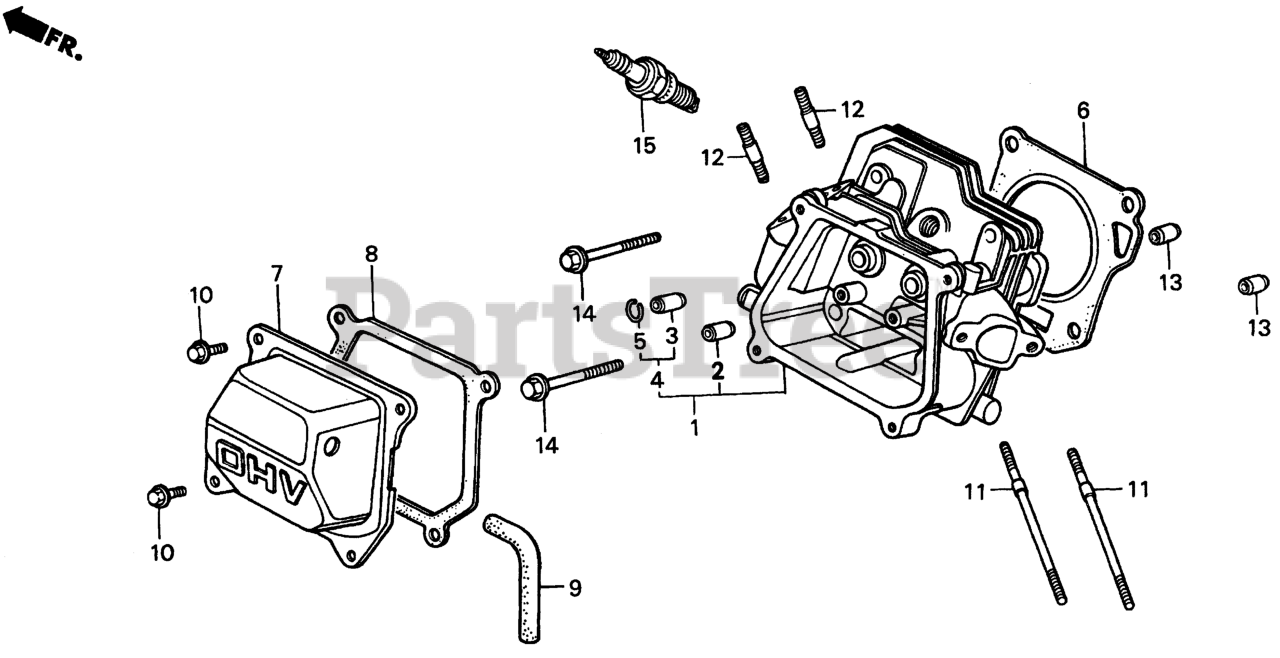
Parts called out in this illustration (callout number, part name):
1	CYLINDER HEAD
2	GUIDE, VALVE (OVER SIZE) Use up to Engine SN 2416541.
3	GUIDE, EX. VALVE (OVER SIZE)
5	CLIP, VALVE GUIDE Use from Engine SN 1231803.
6	GASKET, CYLINDER HEAD
7	COVER, HEAD
8	GASKET, CYLINDER HEAD COVER
9	TUBE, BREATHER
10	BOLT, FLANGE (6X13)
11	BOLT, STUD (6X109)
12	BOLT, STUD (8X32)
13	PIN A, DOWEL (10X16)
14	BOLT, FLANGE (8X60)
15	SPARK PLUG (BPR5ES) (NGK)
15	SPARK PLUG (W16EPR-U) (DENSO)
